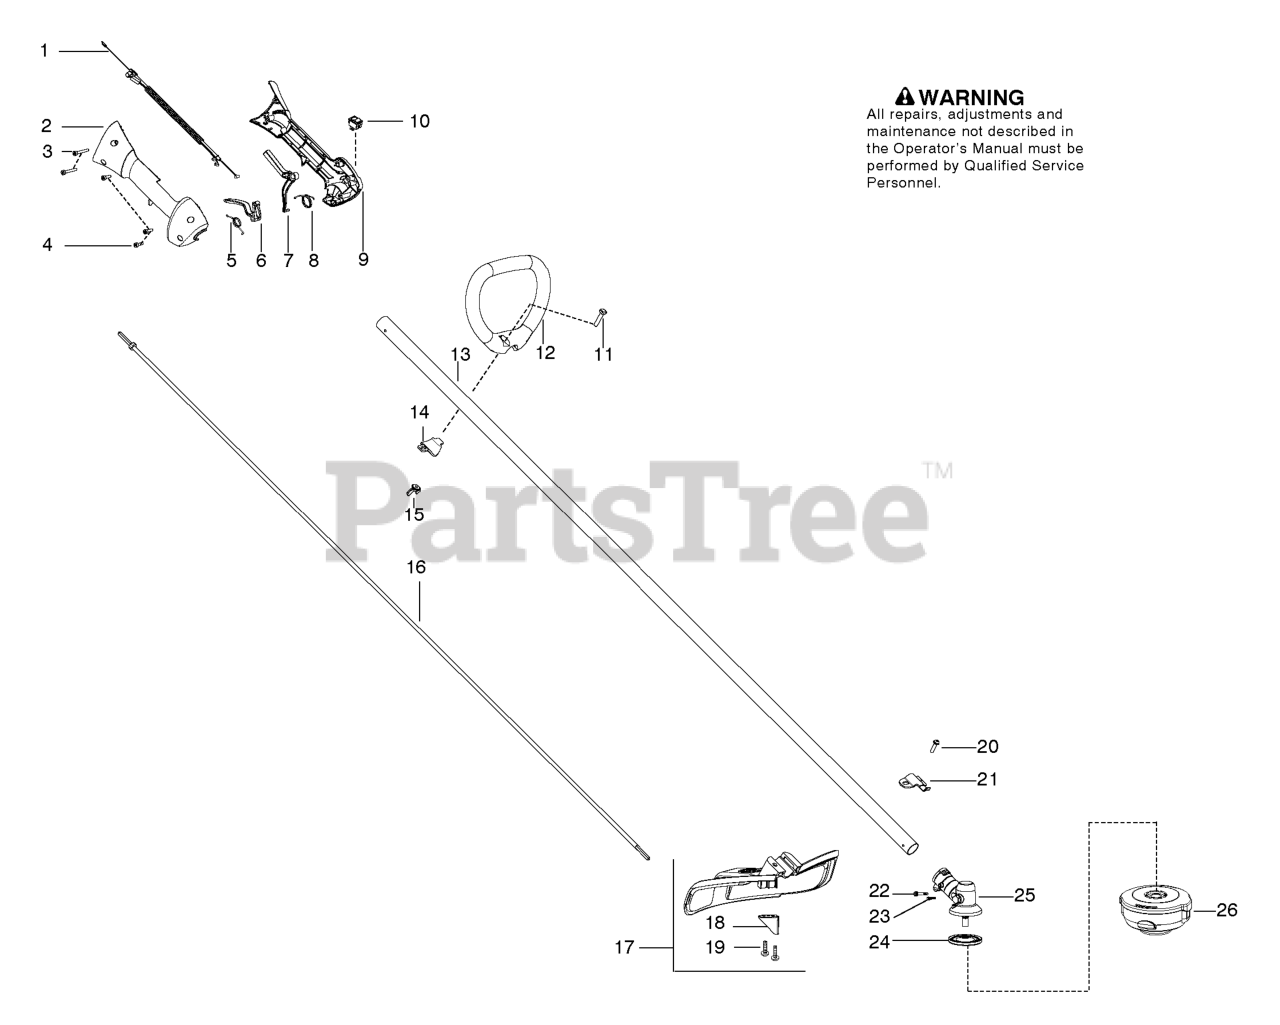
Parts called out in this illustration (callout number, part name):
1	%ASSY CABLE WIRE HARNESS
2	THROTTLE HSG RH
4	SCREW M4 X 1.75 PT 16MM
5	SPRING TRIGGER
6	TRIGGER
7	THROTTLE LOCKOUT
8	SPRING LOCKOUT
9	THROTTLE HSG LH
10	KIT SWITCH
11	BOLT, TYPE 2
12	HANDLE ASSIST
13	KIT DRIVESHAFT SST
14	CLAMP ASSIST HANDLE
15	WINGNUT, TYPE 2
16	FLEXSHAFT 57"
17	KIT COBI SHIELD
18	Limiter-Line
20	SCREW 1/4-20 X 7/8 (TAP
21	BRACKET SHIELD STRAIGHT SHAFT
22	SCREW - CARB. ADAPTOR
24	ASSY DUST CUP
25	ASSY GEARBOX
26	T25 10MM LH TRIMMER HEAD
